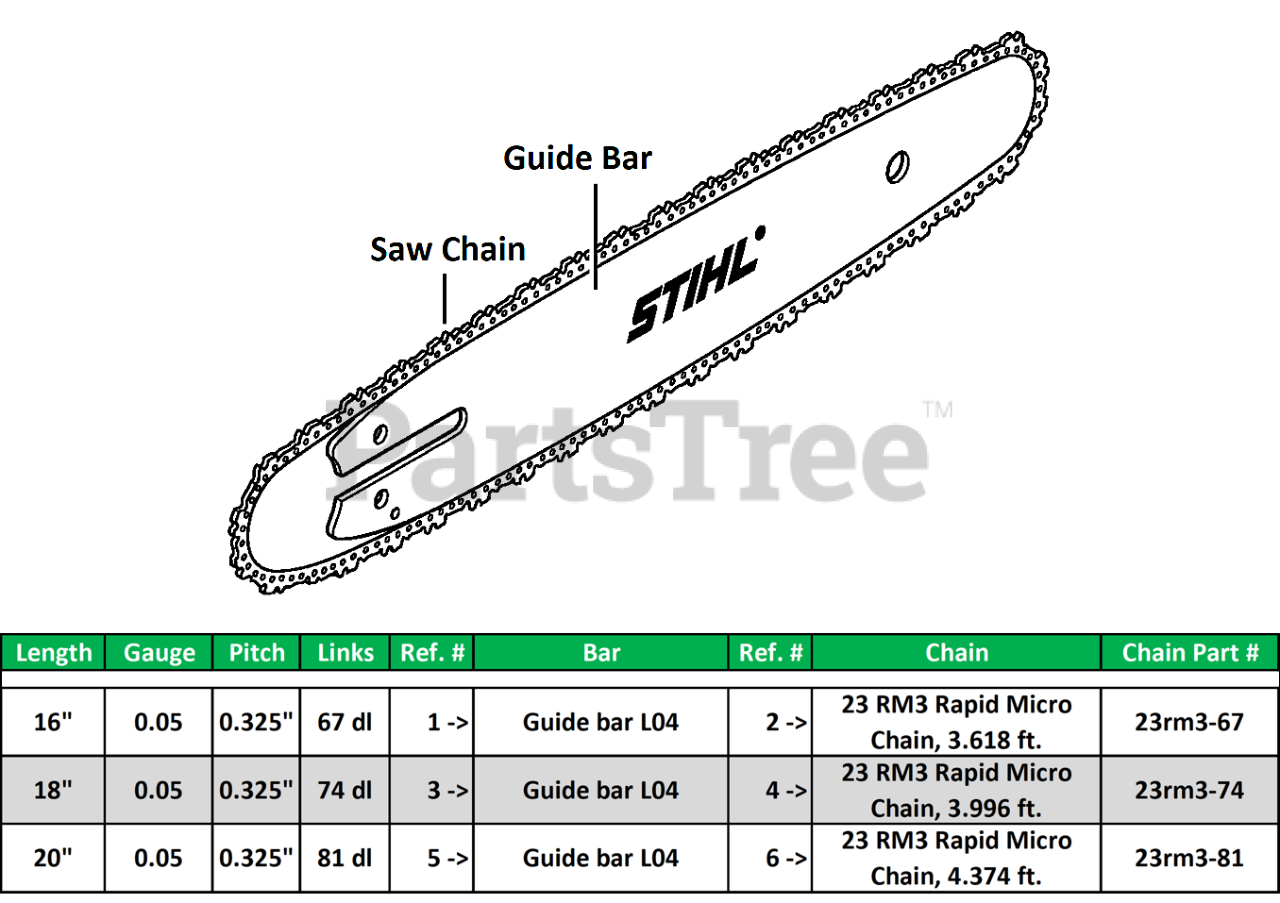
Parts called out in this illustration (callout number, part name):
1	Guide bar L04 40cm/16" 1,3mm/0.050"
2	23 RM3 Rapid Micro Chain, 3.618 ft.
3	Guide bar L04 45cm/18" 1,3mm/0.050"
4	23 RM3 Rapid Micro Chain, 3.996 ft.
5	Guide bar L04 50cm/20" 1,3mm/0.050"
6	23 RM3 Rapid Micro Chain, 4.374 ft.
